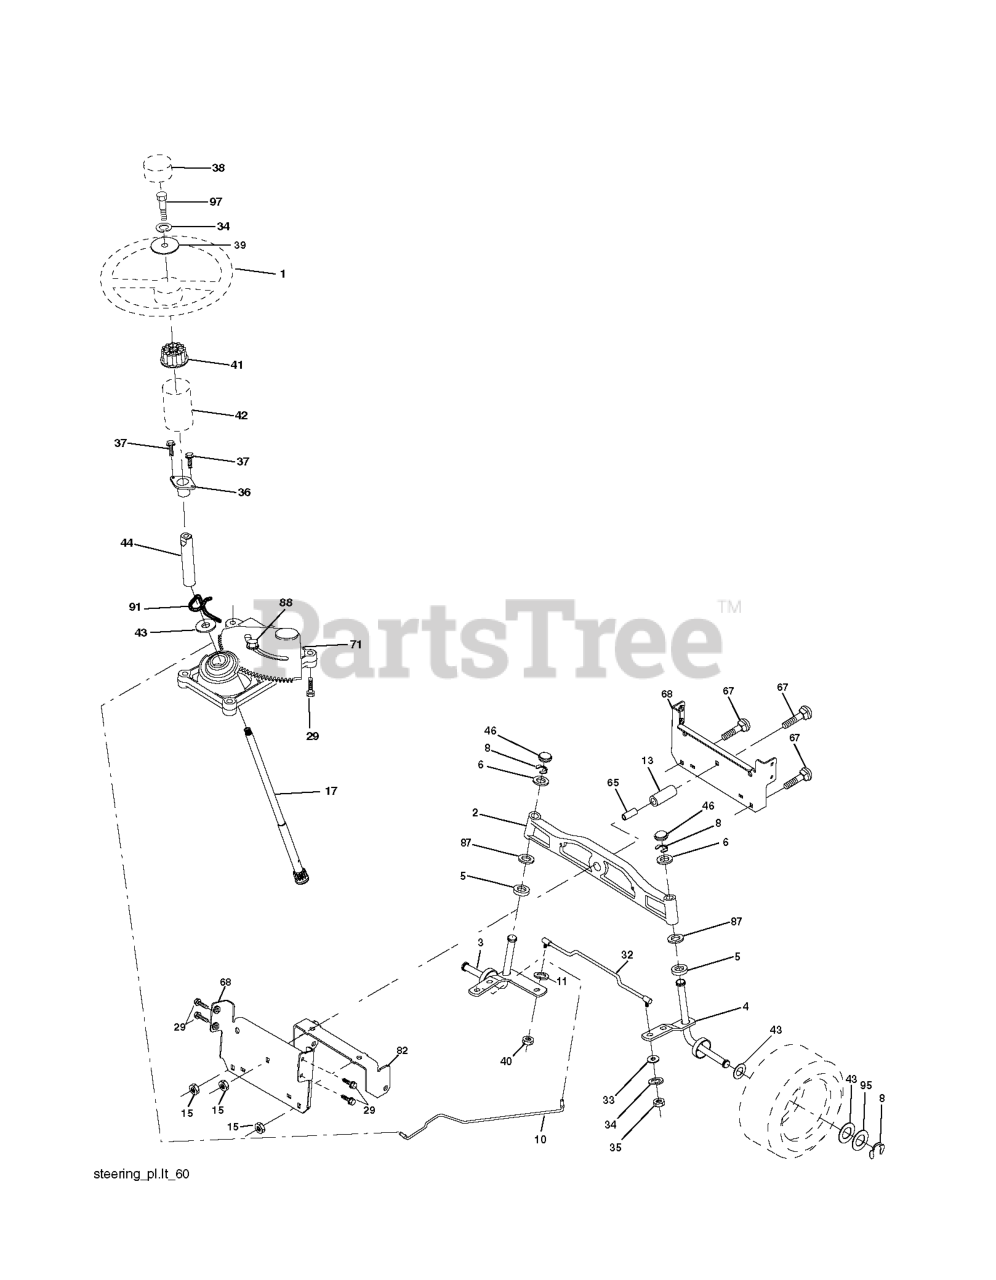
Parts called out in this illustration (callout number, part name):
1	STEERING WHEEL
2	AXLE ASSY FRONT
3	SPINDLE.ASM.LH.15"TIRES
4	SPINDLE.ASM.RH.15"TIRES
5	THRUST WASHER
10	DRAGLINK.15".TIRES.2001
11	WASHER, LOCK 3/8
13	TUBE, PIVOT AXLE
15	NUT
17	SHAFT STEERING SPLINE
29	SCREW, 3/8-16X3/4
33	WASHER M
34	WASHER.LOCK.HVY.HLCL.SPR.5/16
35	NUT, CROWNLOCK
36	BUSHING, STEERING
37	SCREW.TT.#10-32X.5.3/8.FLANGE
38	INSERT.CAP.STRG.WH.GRAY
39	WASHER.11/32
40	NUT CROWNLOCK 3/8-24
41	ADAPTER, WHEEL STNG..
42	BOOT, STEERING
44	SHAFT.EXTEN.STRG.SPLINE
46	CAP.SPINDLE.BLACK
65	SPACER BRACE AXLE
67	BOLT CARRIAGE
68	BRACE.AXLE.15"TIRES
71	STEERING ASM
82	BRACKET.SUSP.CHASSIS.FRONT.15
87	WASHER, FLAT .781 X 1 1/2"
88	BOLT, SHOULDER 7/16-20
91	CLIP.STEERING
95	WASHER.HARDENED
